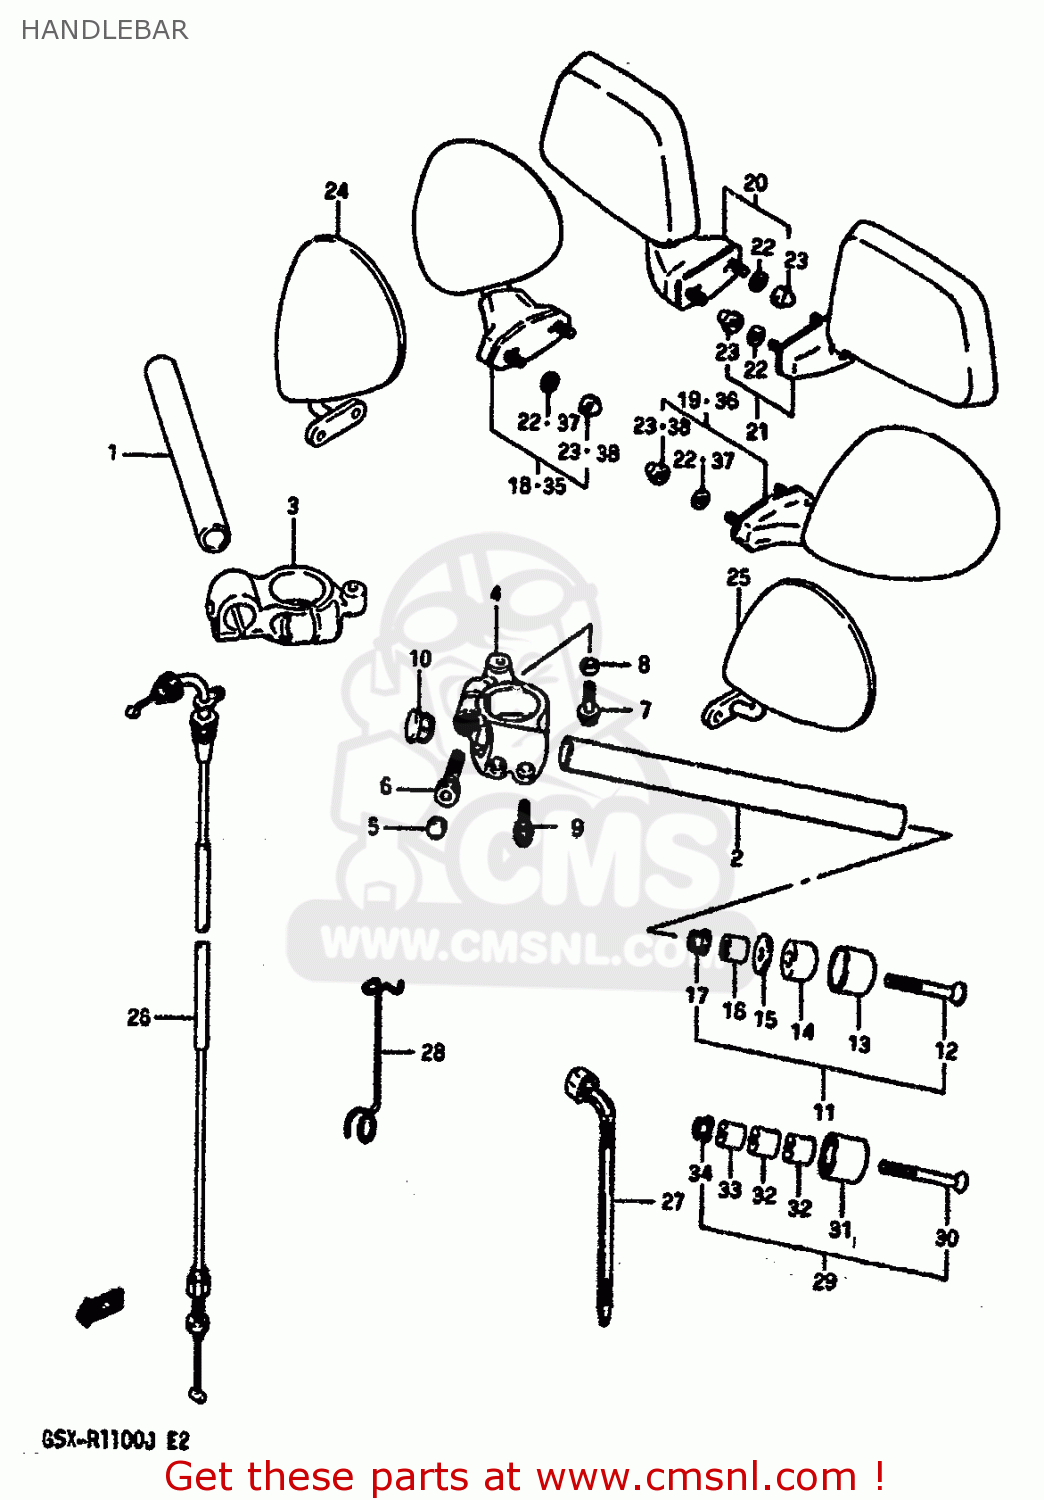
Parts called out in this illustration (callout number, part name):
1	HANDLEBAR,R
2	HANDLEBAR,LEFT
3	HOLDER,HANDLEBAR,RIGHT
4	HOLDER,HANDLEBAR,LEFT
5	CAP(OD:10)
6	BOLT 8X35
7	BOLT
8	SPACER (6.1X9X3.8)
9	BOLT,HANDLEBAR
10	CAP,HANDLEBAR
11	BALANCER SET,HANDLEBAR
12	SCREW
13	CAP,BALANCER
14	BALANCER,HANDLE
15	SPACER,BALANCER
16	EXPANDER,HANDLE BALANCER
17	NUT
18	MIRROR ASSY,RE
19	MIRROR ASSY,LH
20	MIRROR,REAR VIEW RH
21	MIRROR ASSY,LH
22	WASHER
23	NUT 6MM
24	MIRROR,REAR VIEW RH
25	MIRROR,REAR VIEW LH
26	CABLE ASSY,THROTTLE
27	CLAMP(L:165)
28	GUIDE,SUB T/M CABLE
29	BALANCER SET,HANDLEBAR
30	SCREW(6X85)
31	CAP,BALANCER
32	BALANCER,HANDLEBAR INNER
33	EXPANDER,HANDLE BALANCER
34	NUT
35	MIRROR ASSY,REAR VIEW RH
36	MIRROR ASSY,REAR VIEW LH
37	WASHER
38	NUT 6MM
